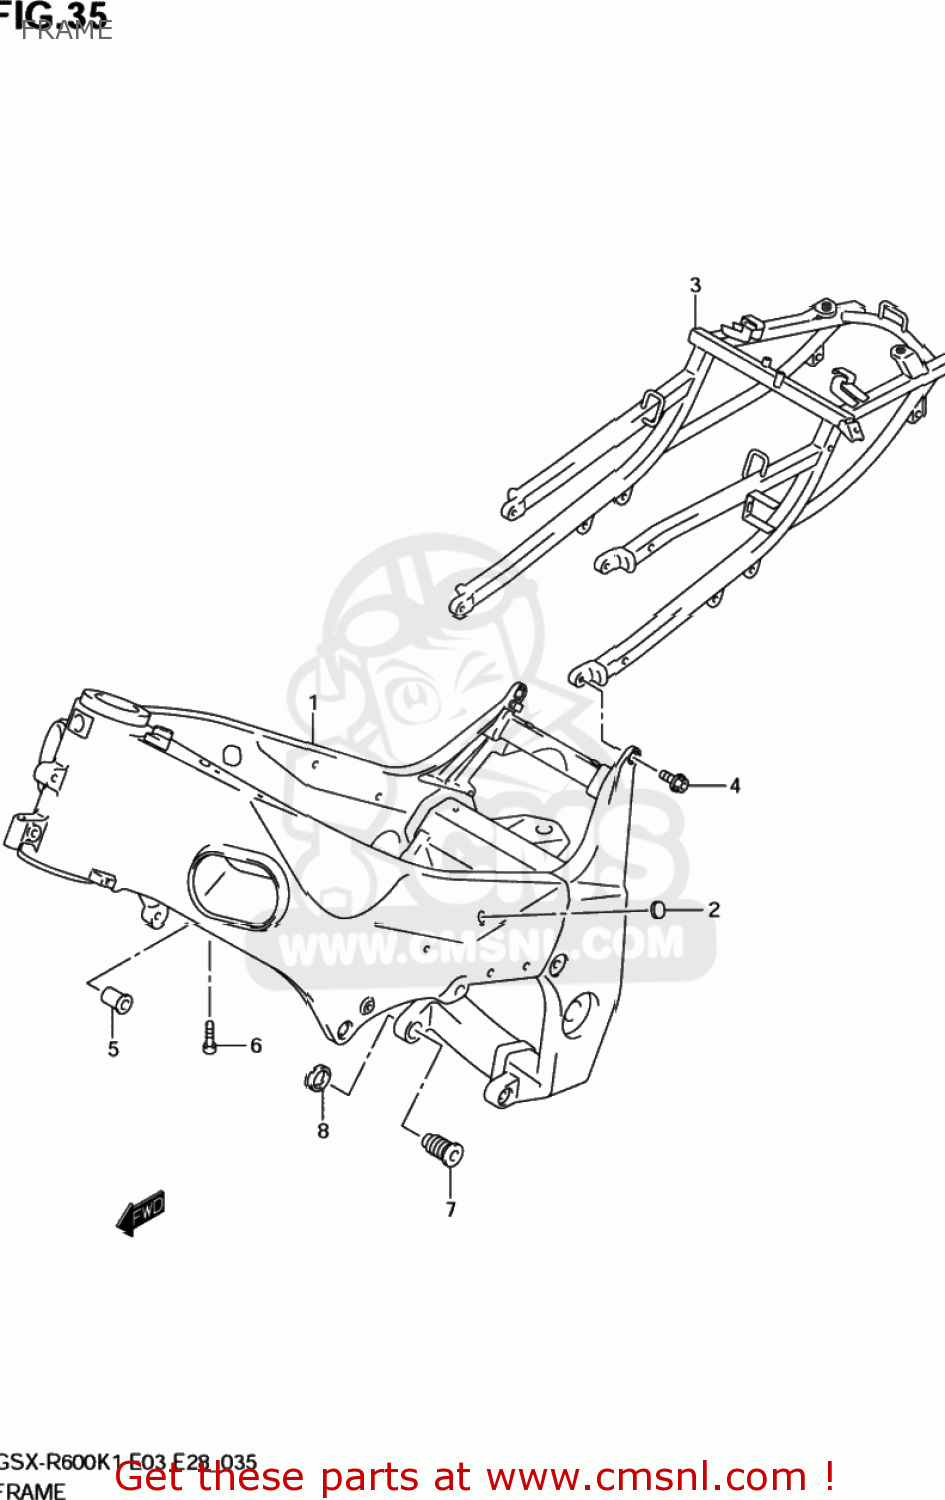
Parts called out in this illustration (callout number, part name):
1	FRAME COMP
2	CAP,TANK RAIL
3	RAIL COMP,SEAT
4	BOLT,SEAT RAIL
5	SPACER,ENGINE MOUNTING
6	BOLT
7	BOLT,CRANKCASE ADJUST
8	NUT,CRANK CASE ADJUST BOLT
